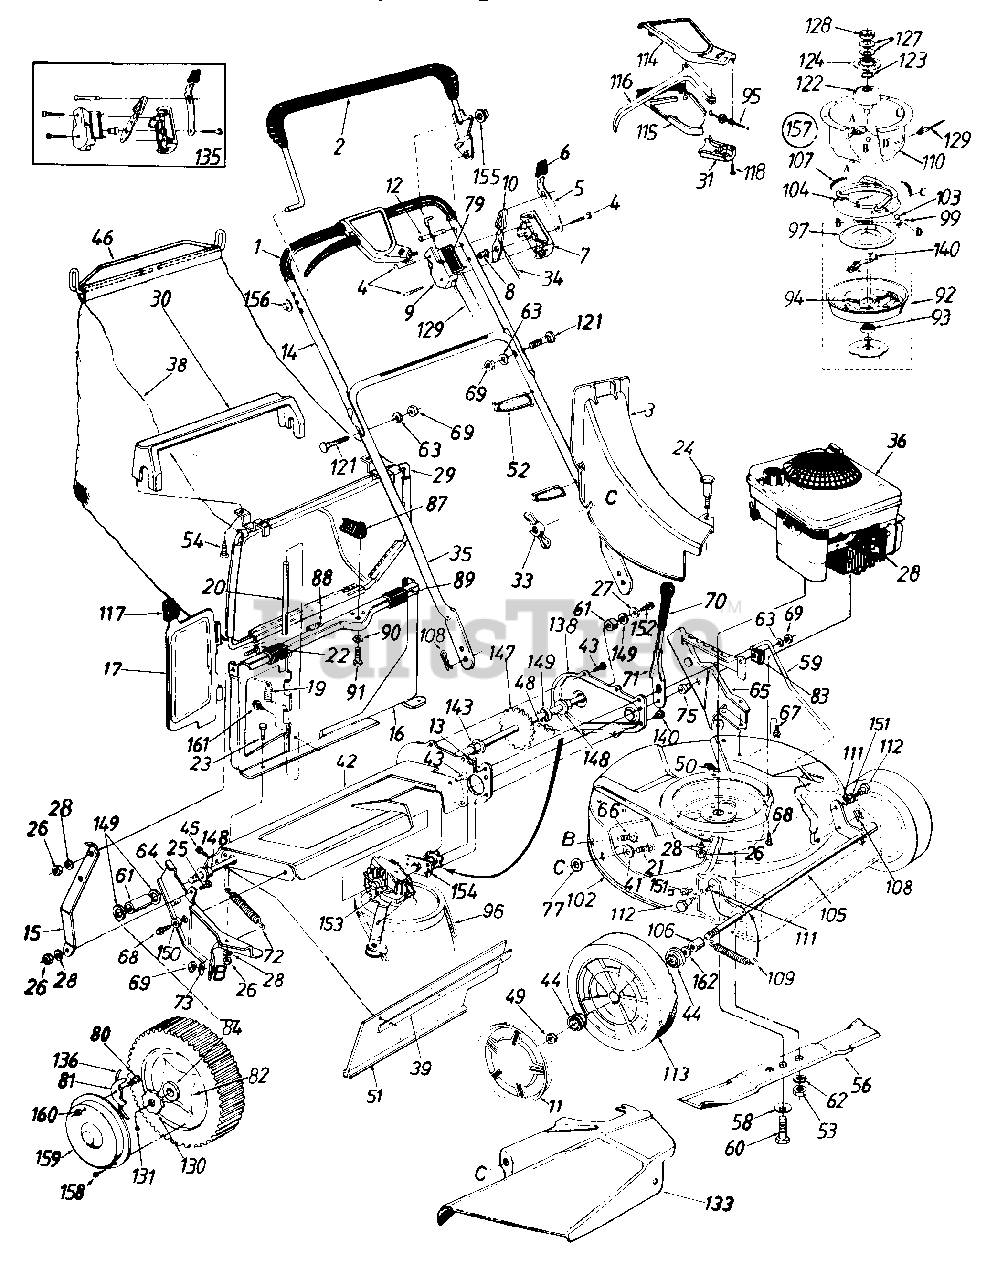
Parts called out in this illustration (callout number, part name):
1	Foam Grip
2	Control Handle Ass'y.-L.H.
3	Top Discharge Chute Ass'y
4	Truss Mach. Scr. #12 x 1.50" Lg.
5	Lockout Spring
6	Spring Lever Knob
7	Control Panel Half
8	Control Disc Pin
9	Clutch Panel Half
10	Throttle Control Lever
11	Hub Cap
12	Lock Pin .314" Dia. x 1.75"
13	Cotter Pin 3132" Dia. x .75"*
14	Upper Handle
15	Panel Support Brkt.
16	Top Catcher Panel Ass'y.
17	Top Discharge Door
19	Torsion Spring
20	Pivot Pin
21	Carriage Bolt 1/4-20 x .62"*
22	Truss Mach. Scr. 1/4-20 x .5" Lg.
23	Hex Bolt 1/4-20 x .50" Lg.
24	Shoulder Bolt .312 Dia. x .18 Lg. Special
25	Hex Bolt 1/4-20 x .62" Lg.
26	Hex Nut 1/4-20 Thd.
27	Bell-Wash. 1/4" I.D.
28	L-Wash. 1/4" I.D.*
29	Front Grass Catcher Frame
30	Grass Catcher Handle
31	S.P. Control Cover
33	Wing Nut
34	Throttle Control Wire 61" Lg.
35	Lower Handle
36	Engine
38	21" Top Discharge Grass Bag-Black
39	Retaining Strip
41	Fl-Wash. .344" I.D. x .62"
44	Flange Ball Bearing 1/2" I.D.
45	Hex AB-Tap Scr. 1/4 x .62"
46	Upper Bag Handle
48	#48 Chain .500" Pitch x 30 Links
49	Hex L-Nut 1/4-20 Thd.
51	Rear Flap 3.75" x 17.30" Lg.
52	Cable Tie
53	Hex Nut 3/8-24 Thd. (Grade 8)
54	Hex AB-Tap Scr. #12 x 1.0" Lg.
56	21" Blade
58	Bell-Wash. .46" I.D. x .88" O.D.
59	Height Adj. Rod 19.42" Lg.
60	Hex Bolt 7/16-20 x 2.0" Lg. (Grade 5)
61	Spacer .513" I.D. x .703" O.D. x .69" Lg.
62	L-Wash. 3/8" I.D.
63	L-Wash. 5116" I.D.*
64	R.H. Handle Wheel Brkt. Ass'y.
65	L.H. Handle Wheel Brkt. Ass'y.
66	Carriage Bolt 5/16-18 x .62"*
67	Hex Wash. Hd. B-Tap Scr. 5/16-18 x .5" Lg.
68	Hex Wash. Hd. TT-Tap Scr. 3/8-16 x 1.0" Lg.
69	Hex Nut 5/16-18 Thd.
71	Height Adj. Lever
72	Extension Spring .50" O.D. x 3.80" Lg.
73	Bell-Wash. 5/16" I.D.
75	Shld. Spacer .500" Dia. x .100
77	Bolt Retainer 1/4 x .50" O.D.
79	Control Label
80	Shld. Scr. .342" Dia. x .268
81	Pawl
82	Wheel Ass'y. Comp.
83	Clamp
84	Flange Ball Bearing 1/2" I.D.
87	Grass Catcher Locking Knob
88	Foam Strip 1" Lg.
89	Panel Clip
90	Spring Wash. .32" I.D.
91	Hex Wash. TT-Tap Scr. 1/4-20 x .75" Lg.
92	Clutch Blade Housing Ass'y.
93	Ball Brg. .669" I.D. x 1.574"
94	Comp. Spring .35" O.D. x 2.0" Lg.
95	S.P. Cable x 48" Lg.
96	"V"-Belt
97	Clutch Cone
99	Ball Block
104	Brake Cup Cone
105	Front Axle Ass'y.
106	Sleeve .526" I.D. x .690" O.D. x .880" Lg.
107	Ext. Spring 1.75" Lg.
108	Intern. Cotter Pin 5/16" Dia.
109	Extension Spring .50" O.D. x 3.20" Lg.
110	Clutch Housing
111	Intern. L-Wash. 3/8 I.D.*
112	Shld. Bolt .623" Dia. x .425
113	Wheel Ass'y. Comp.
114	Self-Propelled Control Cover
115	Self-Propelled Control Cover
116	Control Lever
117	Door Grip
118	Fl-"C"-Sunk Hd. Tap Scr. #10 x .75" Lg.
121	Curved Carr. Bolt 5/16-18 x 1.38" Lg.
122	Fixed Pulley Adapter
123	Serrated Washer 1.0" I.D.
124	Serrated Pulley Half
127	Bell-Wash. 1.01" I.D.
128	Crankshaft Spacer
129	Control Cable-49" Lg.
130	Ratchet Wheel 1.62" O.D.
131	Cotter Pin 1/8" Dia. x 1.00" Lg.
133	Side Chute Deflector Ass'y.
135	Kit-Control Housing Comp.
136	Spring-Nylon
143	Hex Flange Brg. .506" I.D.
147	Rear Shaft Ass'y. 21.94" Lg.
148	Hex Flange Bearing .506" I.D. Plastic
149	Fl-Wash. .531" I.D. x .930" O.D.
150	Spacer .383" I.D. x .503" O.D.
151	Flanged Nyliner Brg.
152	Hex Bolt 1/4-20 x .62" Lg. (Grade 5)
153	Transmission Comp.
154	Hex Bearing Cup
155	Push Cap
156	Push Cap
157	Blade Brake Clutch Ass'y. Comp.
158	Pan Hd. Tap Scr. #12 x .50" Lg.
159	Hub Cap
160	Hex Ins. L-Nut 1/4-20 Thd.
161	Hex B-Tap Scr. #10 x .38"
162	Fl-Wash. .51" I.D. x .75" O.D.
